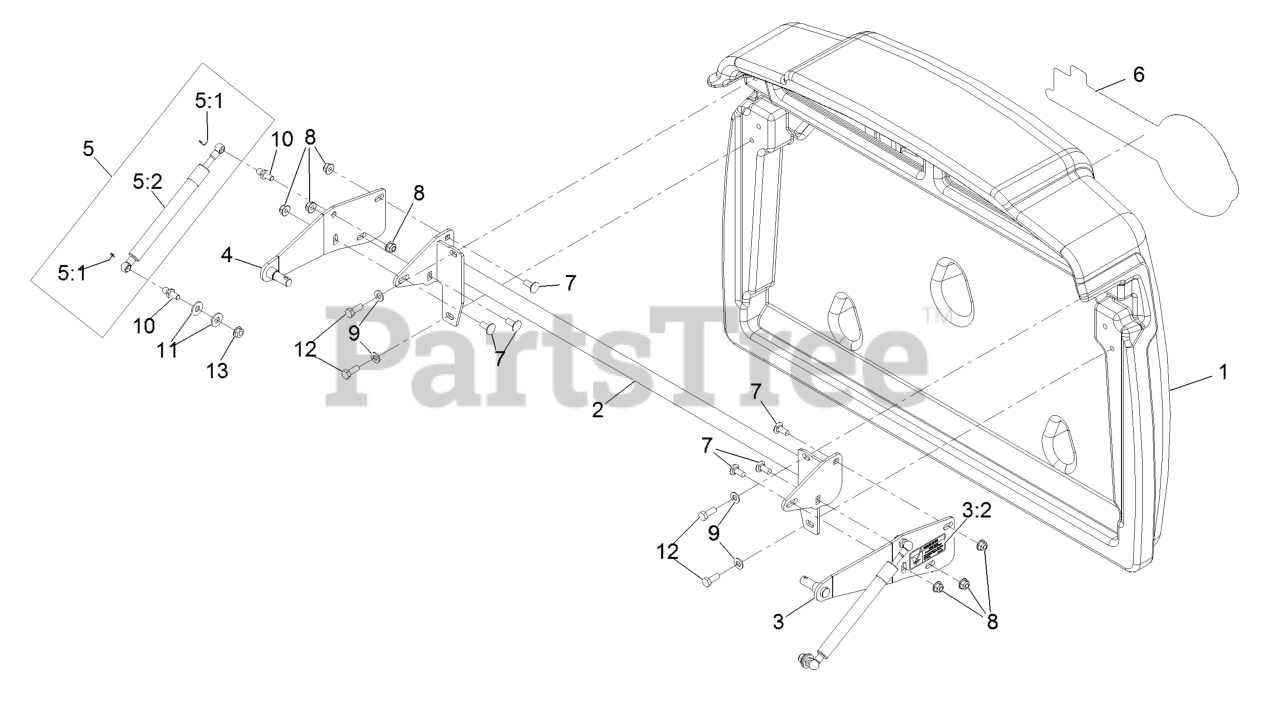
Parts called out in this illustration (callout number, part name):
1	DOOR,HOPPER
2	SUPPORT-DOOR
3	LH DOOR PIVOT ASM
3:2	DECAL-PINCH POINT
4	RH DOOR PIVOT ASM
5	DAMPER KIT
5:1	CLIP-RETAINER
5:2	SHOCK-GAS TENSION
6	DECAL,EXMARK LOGO
7	SCREW-CARR
8	NUT-HF, NI
9	WASHER-PLAIN
10	STUD-BALL
11	WASHER-FLAT
12	SCREW-HH
